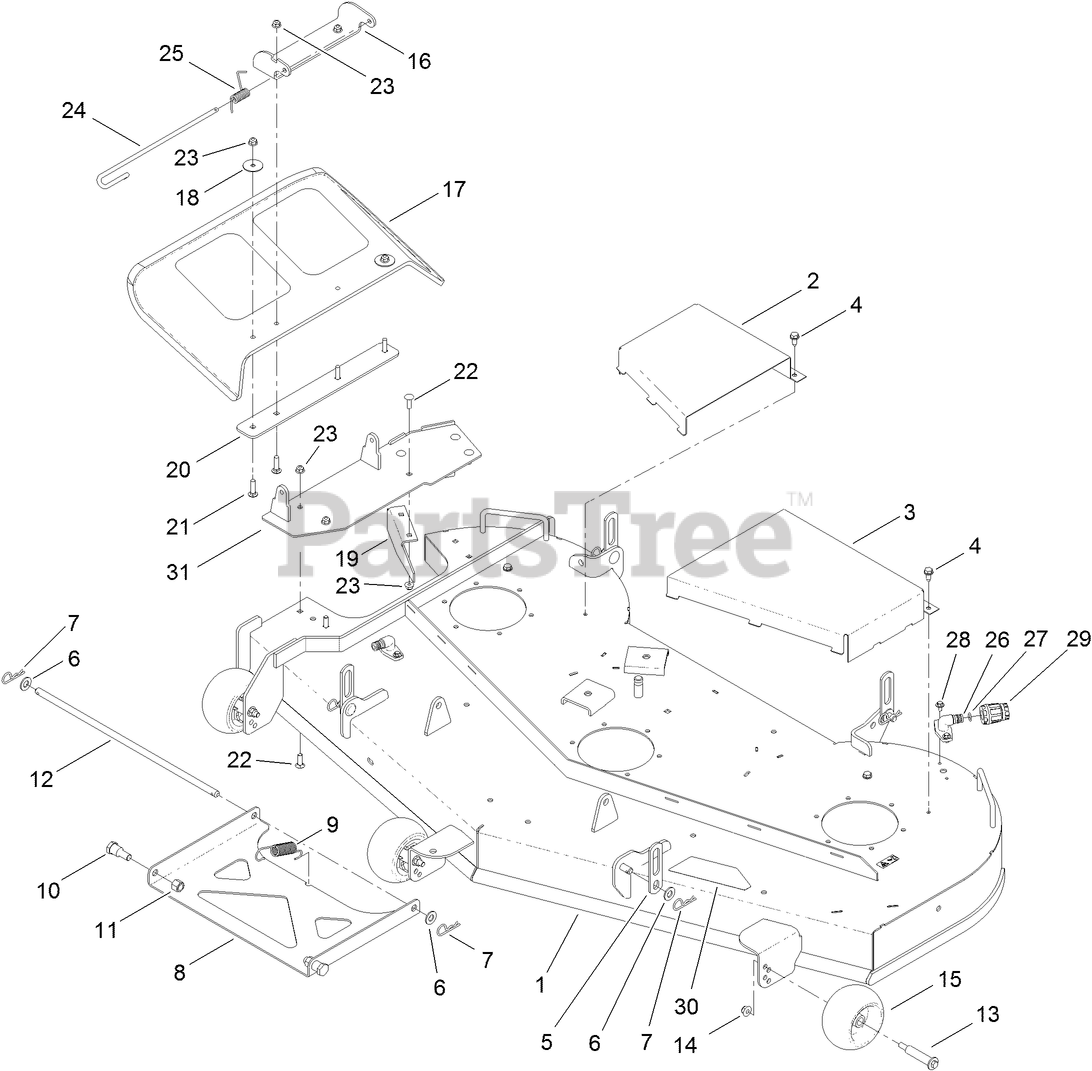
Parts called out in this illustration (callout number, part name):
1	60 INCH DECK ASM
4	SCREW-HWHTF
5	LINK-LIFT
6	WASHER-FLAT
7	PIN-COTTER
8	PAN-PIVOT, DECK
9	SPRING-EXTENSION
11	NUT-LOCK, NI
12	ROD-DECK, PIVOT
13	BOLT-SHOULDER
14	NUT-HF, NI
15	ROLLER-SCALP, ANTI
16	BRACKET-DEFLECTOR, UPPER
17	DEFLECTOR
18	WASHER-FLAT
19	BAFFLE-CUTOFF
20	PLATE-DEFLECTOR
21	SCREW-CARR
22	SCREW-CARR
23	NUT-HF, NI
24	PIN-CHUTE
25	SPRING-TORSION
27	O-RING
28	SCREW-HHFTF
29	CONNECTOR-HOSE
